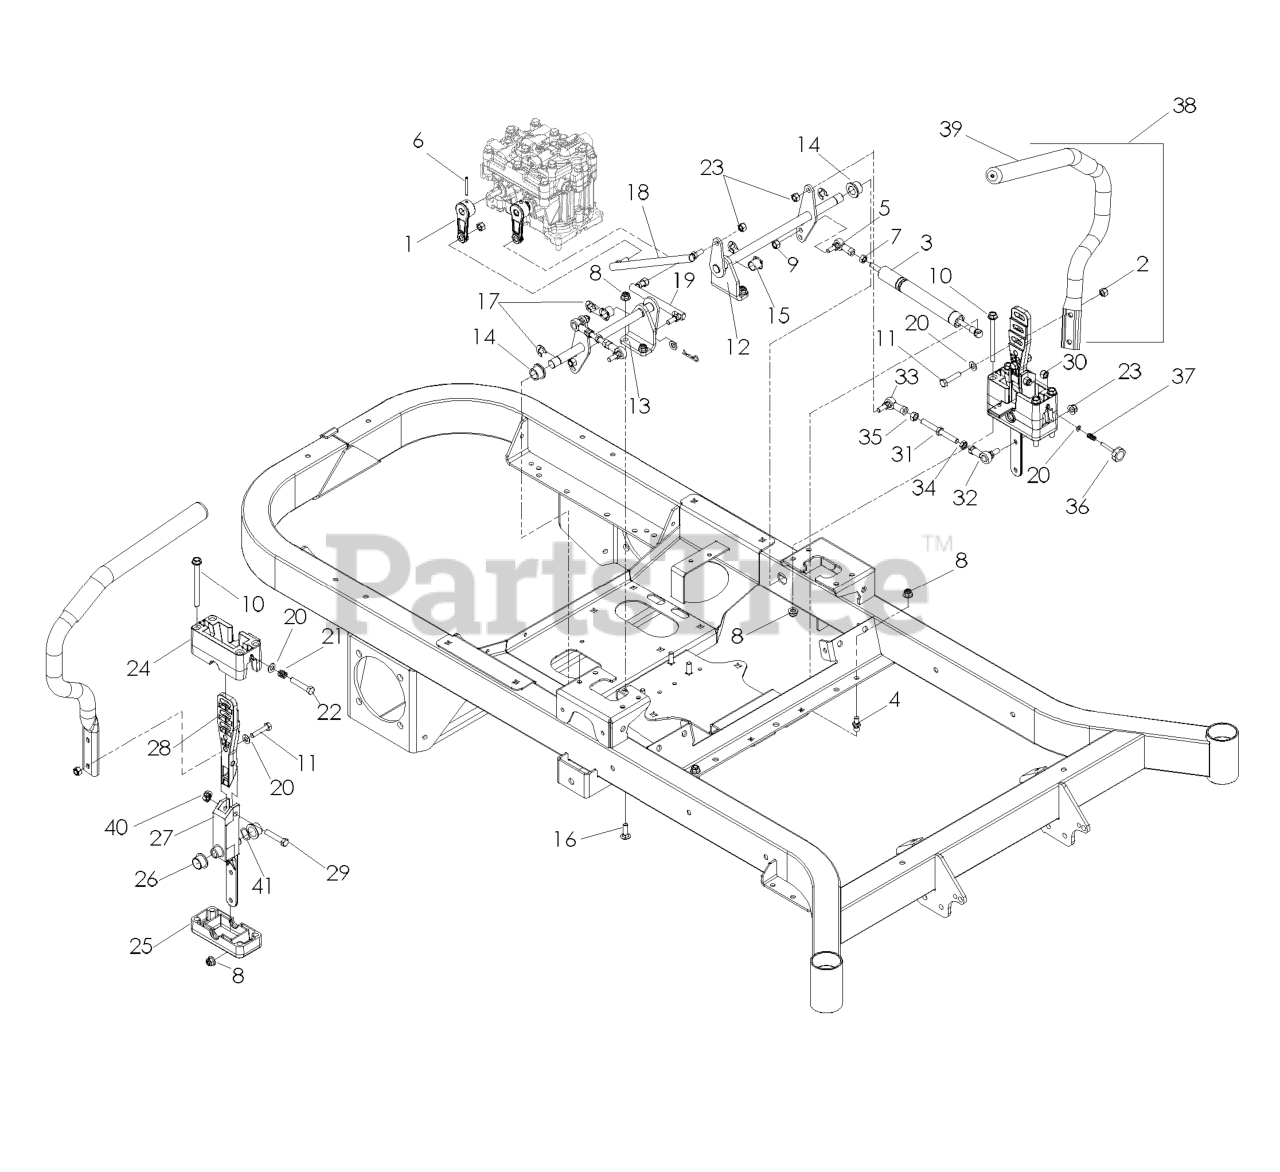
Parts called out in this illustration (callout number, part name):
1	ARM, PUMP
2	NUT 5/16 NYLOC
3	DAMPENER W/SPRING
4	STUD.BALL.10MM
6	PIN, SPIRAL, 5/32 X 1 1/2
7	NUT M8 X 1.25 STD HEX
8	5/16-18 NYLOC FLANGE NUT
9	NUT M8 NYLOC
10	HHFS 5/16-18 X 3 3/4
11	CAPSCREW 5/16 X 1/1/2 HEX HEAD
12	CONTROL WLDMT, LT
13	CONTROL WLDMT, RT
14	BUSHING, FLANGED, 5/8
15	BUSHING, CLIP, 5/8
16	RHSNB 5/16C X 1
17	E-RING 5/8
18	LINK, MOTION, LT
19	LINK, MOTION, RT
20	FLAT WASHER 5/16 SAE
22	HCS 5/16-18X1-3/4 TPBLT
23	NUT 5/16-24 CNTRLK
24	BLOCK, UPPER
25	BLOCK, LOWER
26	BEARING, FLANGE
27	PIVOT SECTION, DR CNTRL
28	MOUNT, DR CNTRL HANDLE
29	HCS 5/16C X 1 3/4
30	NUT 5/16C HEX
31	JACK SCREW
32	SPHERICAL ROD END, LH
33	SPHERICAL ROD END, RH
34	NUT 5/16F LEFTHAND
36	KNOB
38	LEVER.DRIVE.W/GRIP.RIGHT
38	LEVER.DRIVE.W/GRIP.LEFT
39	GRIP - DRIVE LEVER 12"
40	5/16-18 NYLOC FLANGE NUT
41	WASHER, .825 X 1.087, WAVE
